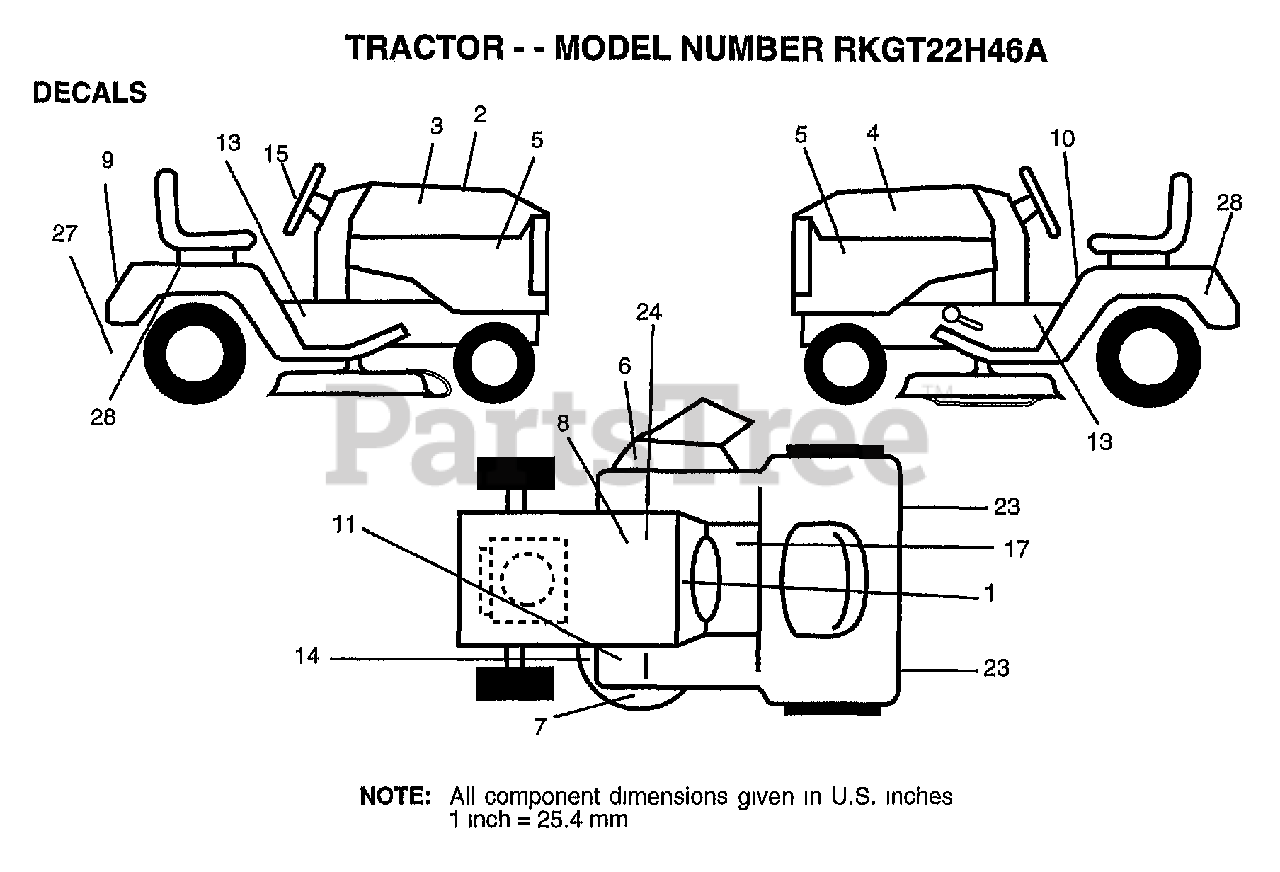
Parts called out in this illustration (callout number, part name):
1	DECAL OPER INSTR.
3	DECAL, HOOD
4	DECAL, HOOD
5	DECAL.DASH
6	"DECAL, WARNING"
7	DECAL.MOWER
9	DECAL.FNDER.LOGO
10	DECAL.CAUT.ENG/FR
11	DECAL T
13	DECAL, CHASSIS
15	DECAL.STRNG.WHL
17	DECAL BRAK PARK
23	REFLECTOR-TAIL YT
24	DECAL.BATRY.3-3908
27	DECAL D-BAR CNTRL
28	DECAL.FENDER.SIDE
